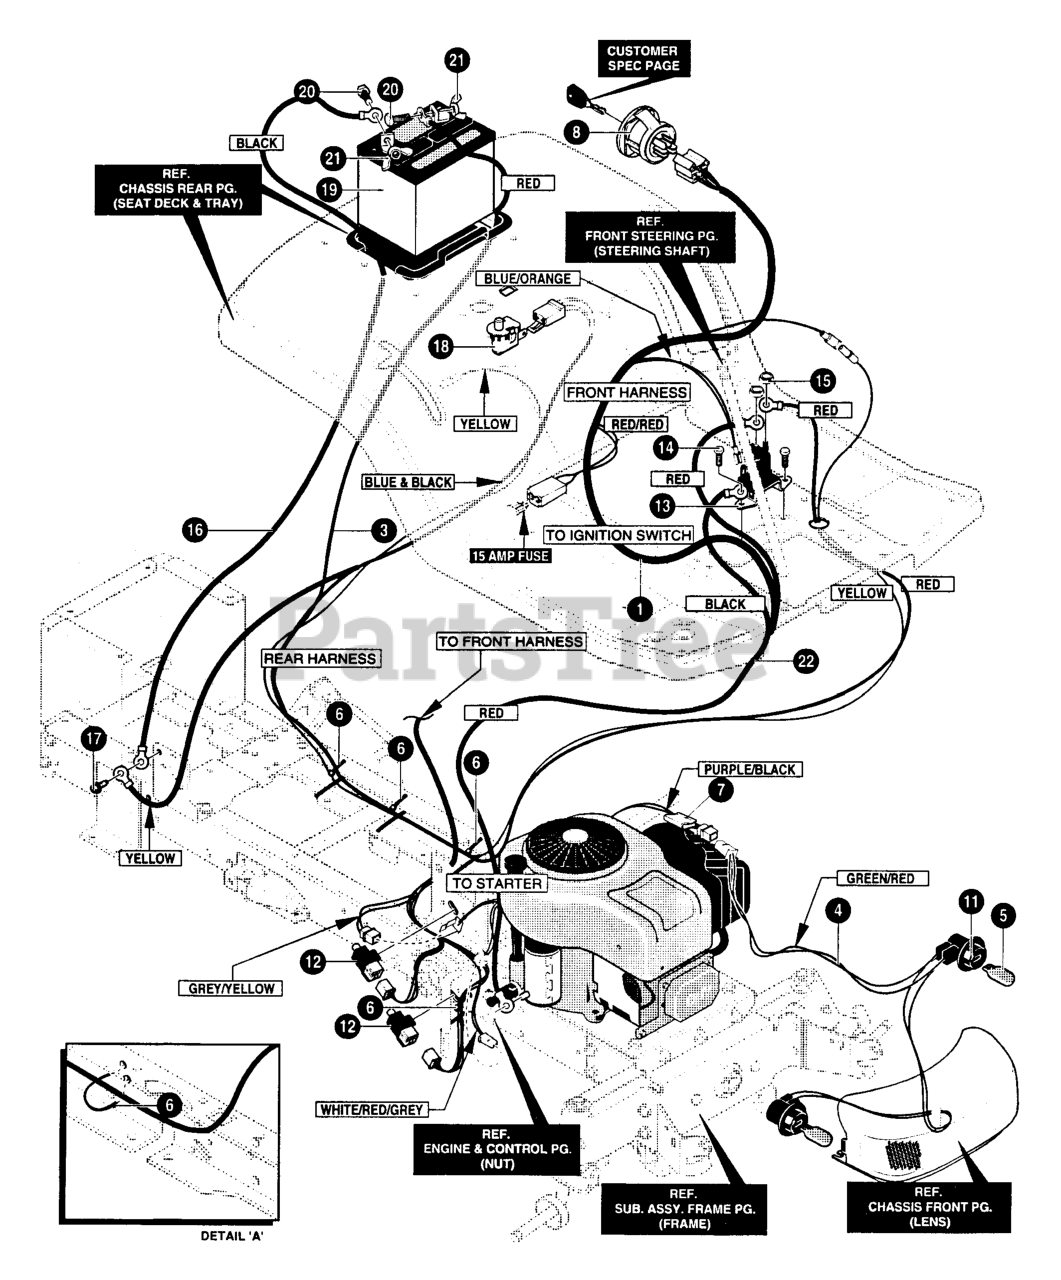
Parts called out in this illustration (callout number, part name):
1	HARNESS, 17HP INTEK
3	WIRE HARNESS, REAR
4	WIRE HARNESS, HEADLIGHTS
5	BULB, HEADLIGHT
6	TIE, CABLE BLACK NYLON 5.62L
7	WIRE CLIP ADHESIVE
8	SWITCH, IGNITION DELTA 7 TERM
9	KEY,IGNITION
11	SOCKET, LAMP
12	SWITCH LIMIT DELTA
13	SOLENOID
14	SCREW,HHWATAP 1/4X.50
15	NUT, 1/4-20 HEXNYL 15X116
16	WIRE, GROUND (24X32)
17	SCREW, HHWATAP 1/4 X.50
18	SWITCH, SEAT
19	BATTERY 6 PLATE
20	BOLT, 1 /4-20X.63CAR
21	NUT, WING 1/4-20 NC (14X79)
22	WIRE, LEAD SOLENOID TO STARTER 1
